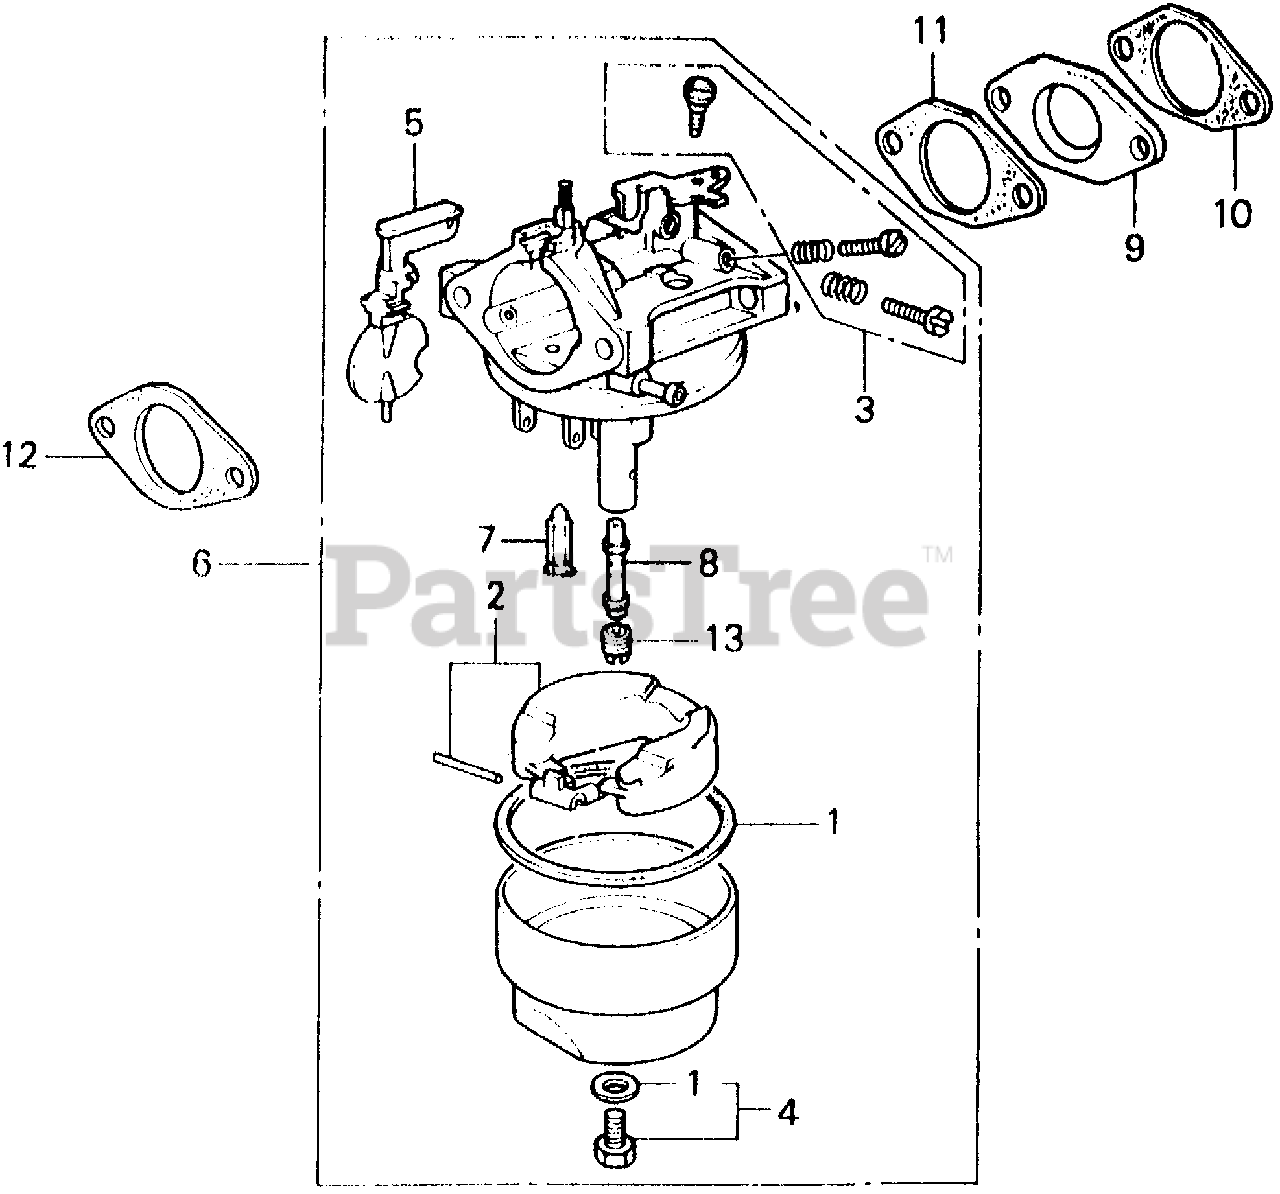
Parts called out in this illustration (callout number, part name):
1	GASKET SET
2	FLOAT SET
3	SCREW SET A
4	SCREW SET B
5	CHOKE SET
6	CARBURETOR ASSY.
7	VALVE, FLOAT
8	NOZZLE, MAIN
9	INSULATOR, CARBURETOR
10	GASKET, INSULATOR
11	GASKET, CARBURETOR
12	GASKET, AIR CLEANER
13	JET, MAIN (#55) Use from Engine SN BB28B A.
13	JET, MAIN (#58) Use from Engine SN BB28B A.
13	JET, MAIN (#60) Use from Engine SN BB28B A.
13	JET, MAIN (#62)
13	JET, MAIN (#65)
